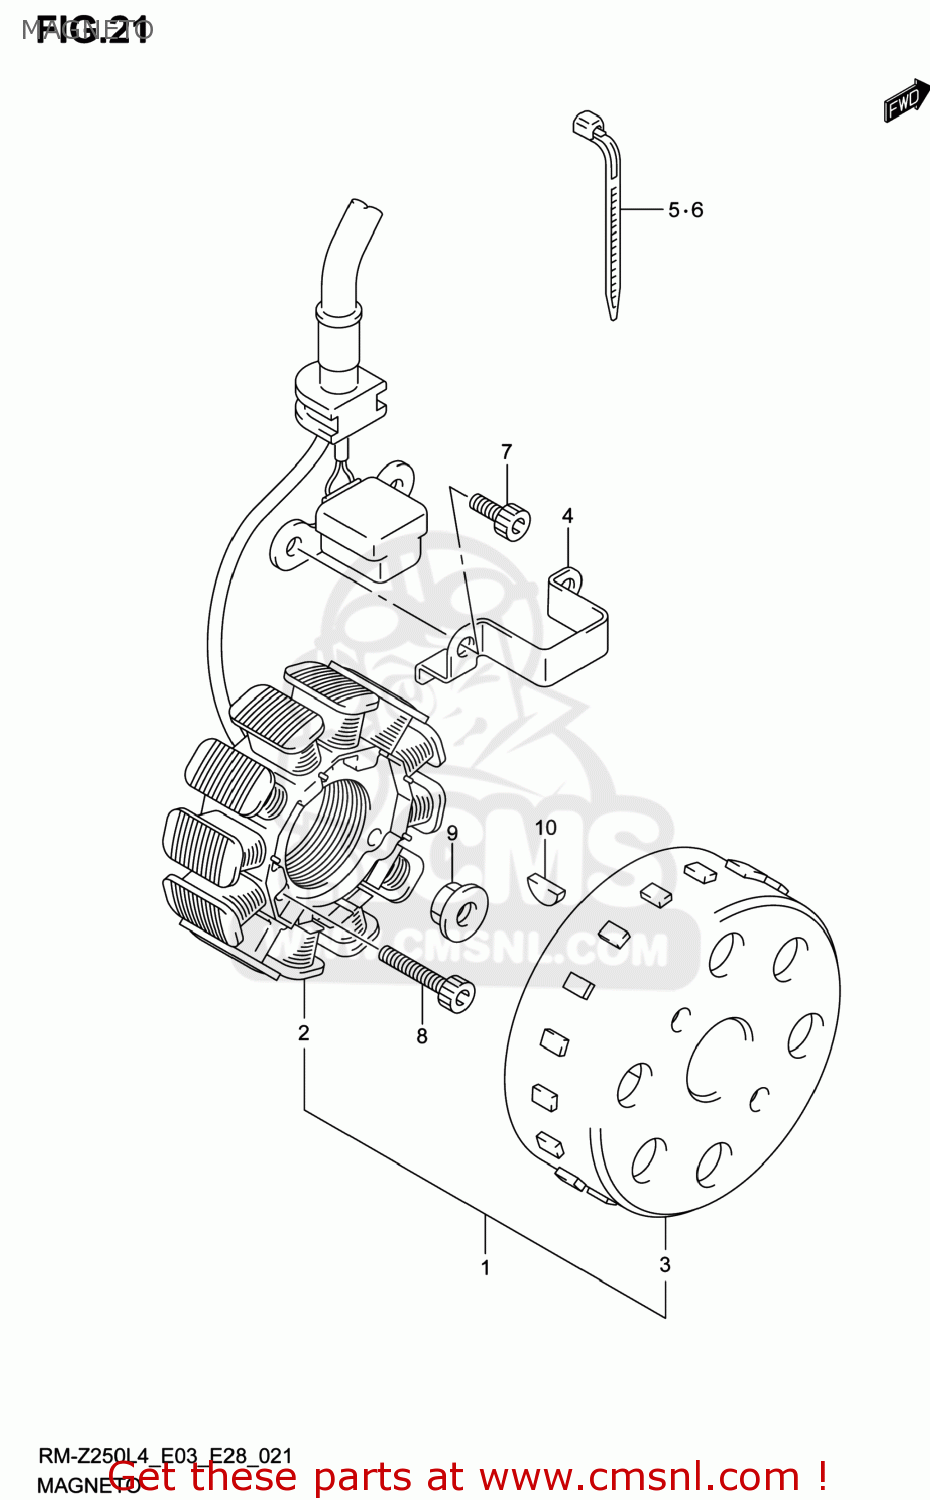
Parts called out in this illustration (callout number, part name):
1	MAGNETO ASSY
2	STARTER ASSY
3	ROTOR ASSY
4	CLAMP,MAGNETO LEAD
5	CLAMP(L:165)
6	CLAMP(L:235)
7	BOLT
8	BOLT
9	NUT
10	KEY
